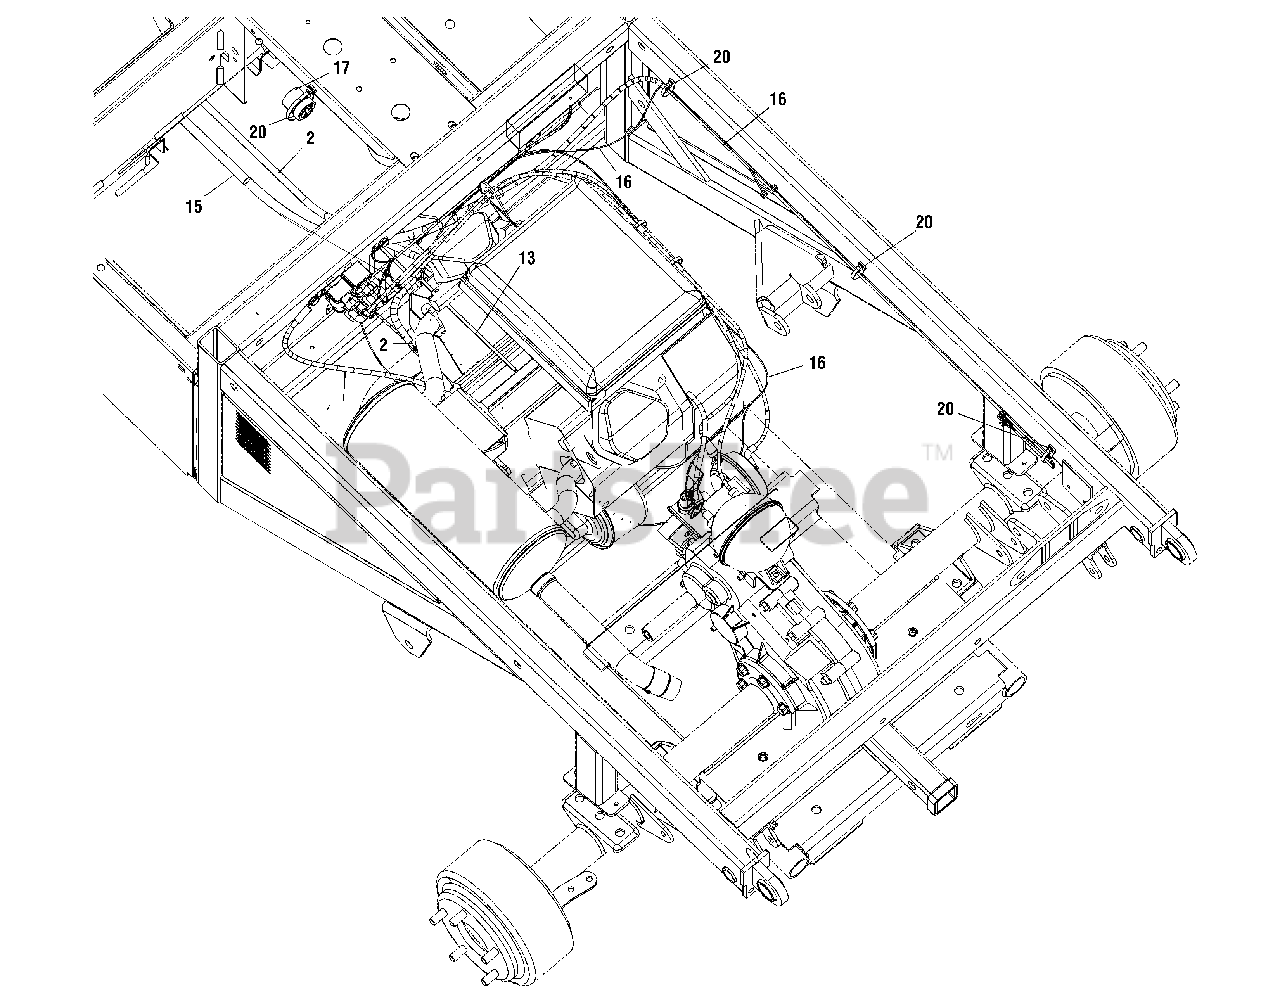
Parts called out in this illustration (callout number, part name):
1	Bracket, Retainer Hook
2	Harness Assembly, Starter
3	Harness Assembly, Motor Ground
4	Screw, 1/4-20 x .50
5	Screw, Self-tapping, 1/4-20 x 0.500
6	Screw, Self-tapping, 5/16-18 x .50
7	Screw, Hex Carriage, 1/4-20 x .75
8	Screw, Self-tapping, 1/4-20 x 1.000
9	Screw, #10-24 x 0.75
10	Nut, Hex Sems, 1/4-20
11	Cover, Protective
12	Strap, Battery
13	Cable Tie, 3/16 x .05 x 7.4
14	Control, Shaft
15	Harness, Utility Main
16	Harness, Motor Kohler
17	Control, Reverse
18	Switch
19	Battery
20	Cable Tie, .19 x 8.39 Tree Mount
21	Lock Washer, 1/4
22	Hourmeater Jumper Harness
23	Pop Rivet.188
24	Lock Washer 1/4 exterbak
25	Fuel Line Hose
